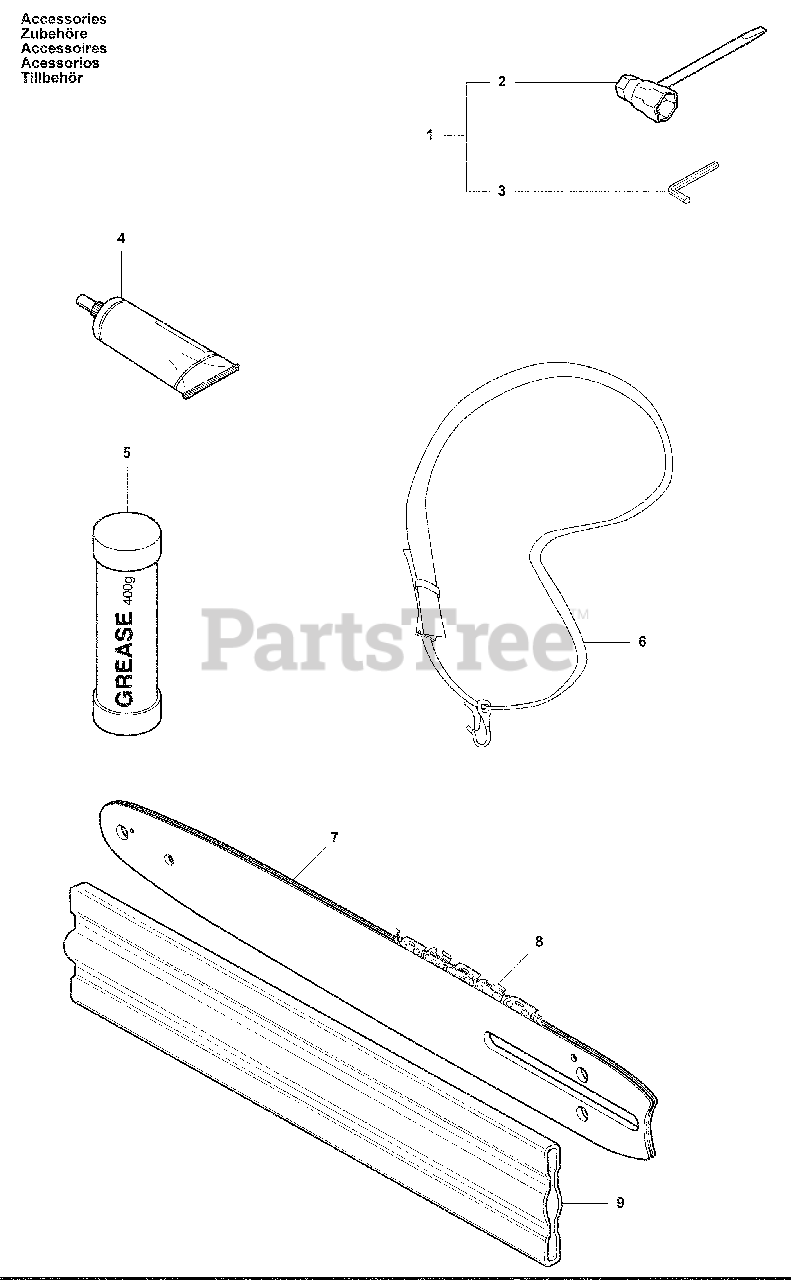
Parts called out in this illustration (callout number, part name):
1	ACCESSORY KIT
2	Combi Tool
3	Allen Wrench, 4mm
4	Gear Grease, Tube
5	GREASE 400 GRAMS
6	Shoulder Strap with Sign
7	Guide Bar, 10" HL280-40 3/8" .050
7	Guide Bar, 12" Hl280-45 3/8 .050
8	H36-40 CHAIN LOOP
8	Saw Chain, 12" H3745 38.050
